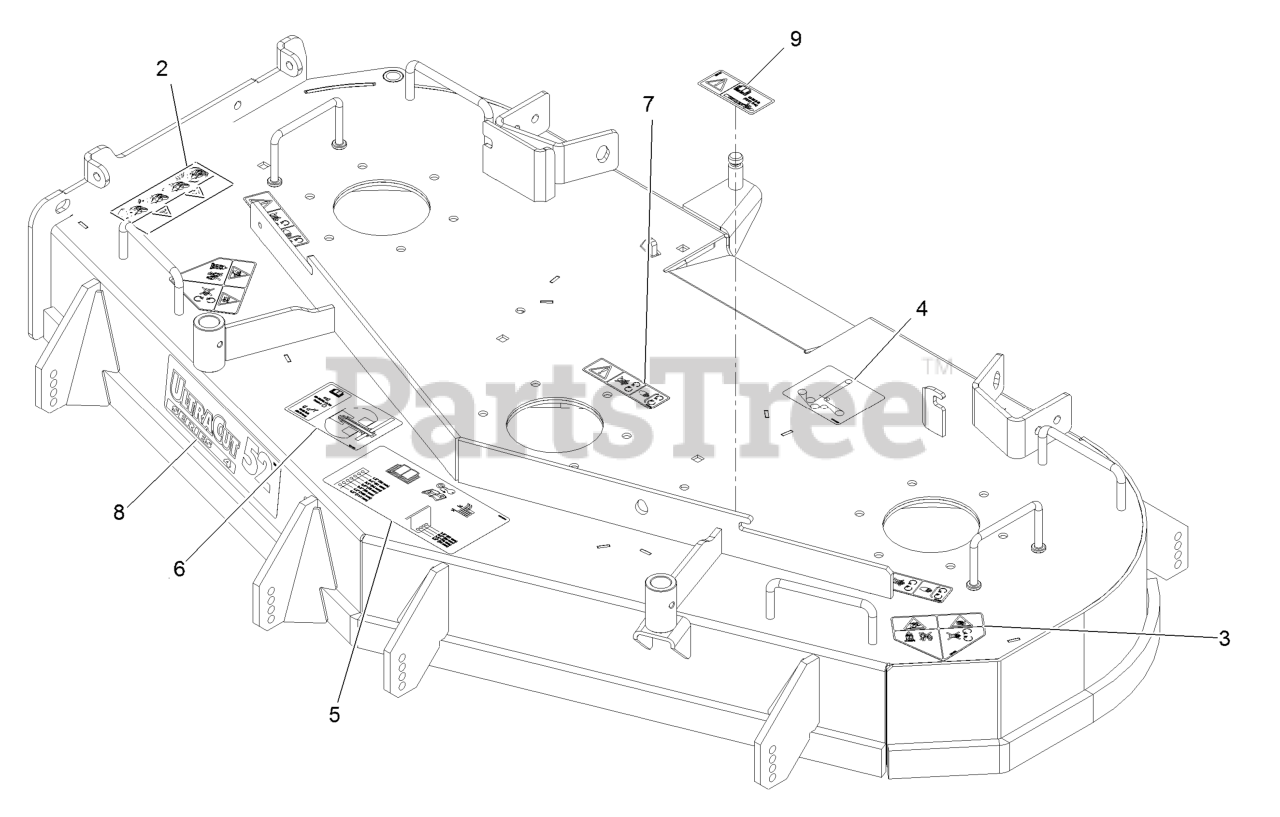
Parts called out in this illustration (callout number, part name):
2	DECAL-WARNING, BAGGER
3	DECAL-DANGER
4	DECAL-BELT ROUTING
5	DECAL-ANTI-SCALP
6	DECAL-ROLLER MOUNTING
7	DECAL-COVER, MISSING
8	DECAL,ULTRACUT 52 SERIES
9	DECAL-BOLT TORQUE
